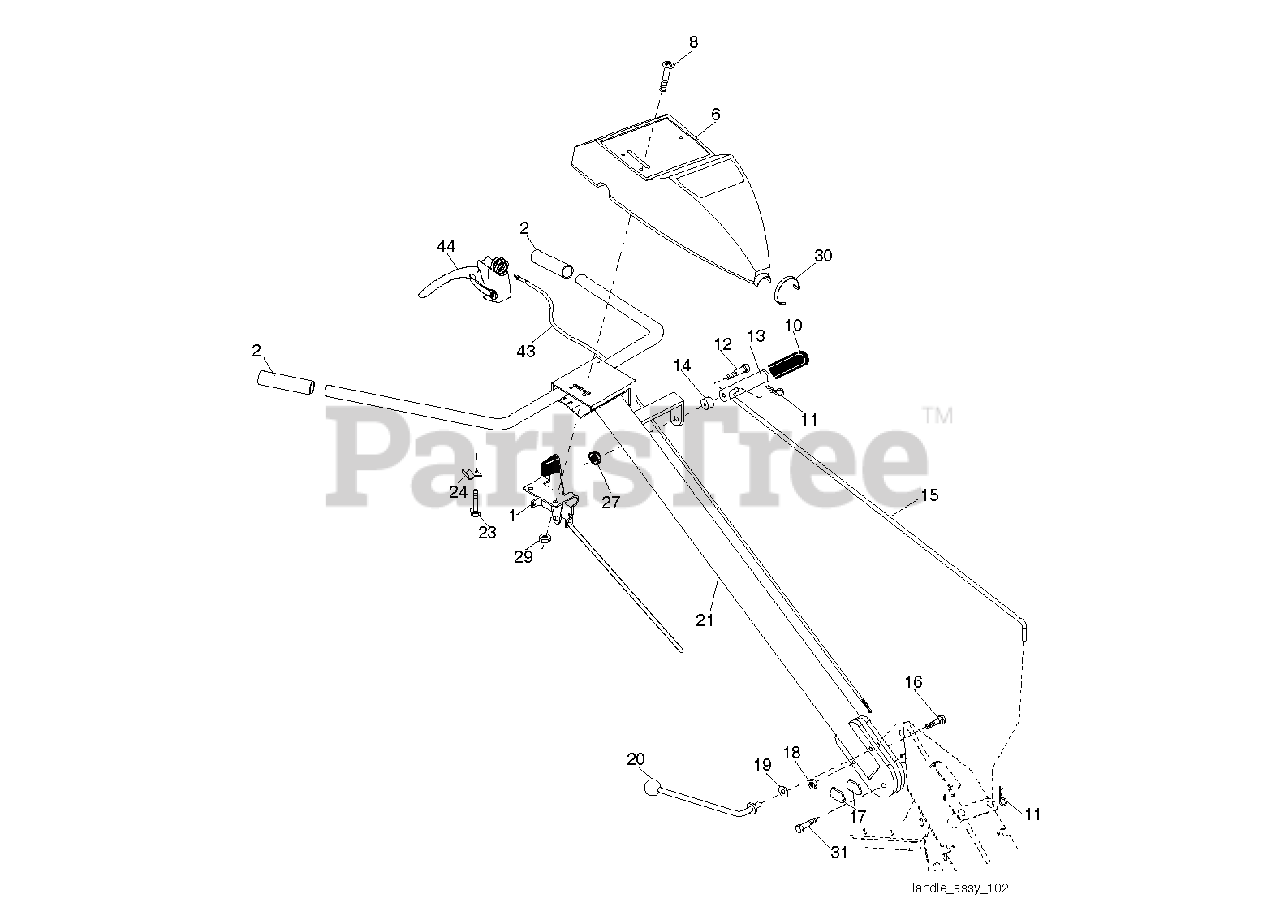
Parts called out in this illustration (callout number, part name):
1	CONTROL.THROTTLE.47.W/Z.BEND
2	GRIP.1X5.06
6	RP CONTROL PANEL
8	SCREW.PNHD.10-24
10	GRIP T
11	RETAINER M
12	SHOULDER BOLT ST
13	HANDLE.SHIFT.TILLER
14	GROMMET.RUBBER.CRT.TILLER
15	ROD.SHIFT.YARD PRO.UNIVERSAL.
16	BOLT D
17	LOCK.HANDLE.CRT
19	WASHER CRT
20	LEVER.LOCK.CRT
21	HANDLE.ASM.TILLER.GREY.
23	TAPPING SCREW
24	CONDUIT.CLIP.PLATED
27	NUT T
29	NUT **
30	TIE CABLE CRT
31	BOLT.PIVOT
43	CABLE.HANDLE.TINE.CONT.RT.CE
44	CONTROL.HANDLE.TWO.FUNCTION.CE
